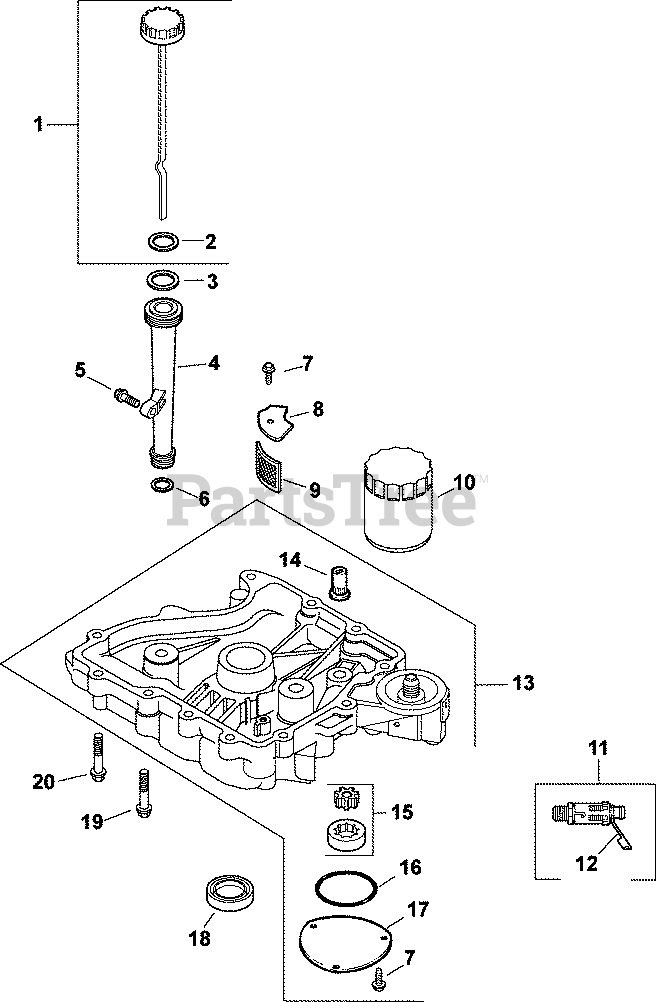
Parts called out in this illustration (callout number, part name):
1	DIPSTICK/CAP ASSY (BLACK)
2	O-RING, DIPSTICK
3	O-RING, UPPER OIL FILL TUBE
4	TUBE, OIL FILL USE 25 123 07-S
5	SCREW,FLG THD FRM M6X1.0X25-(#25086395S)
6	O-RING, LOWER OIL FILL TUBE
7	SCREW,FLG THD FRM M5X0.8X16-(#25086398S)
9	SCREEN, OIL-USE 24 162 26-S
10	OIL FILTER
11	KIT, OIL DRAIN VALVE
12	CAP, OIL DRAIN VALVE
13	PAN, OIL ASSEMBLY - DISCONTNUED
14	VALVE, OIL PRESSURE RELIEF
15	PUMP ASSEMBLY, OIL - DISCONTINUED
16	O-RING (2.5" DIA)
17	COVER, OIL PUMP
18	SEAL, OIL
19	SCREW, HEX FLANGE -USE 24 086 17-S
20	SCREW, FLG M8X1.25X45
